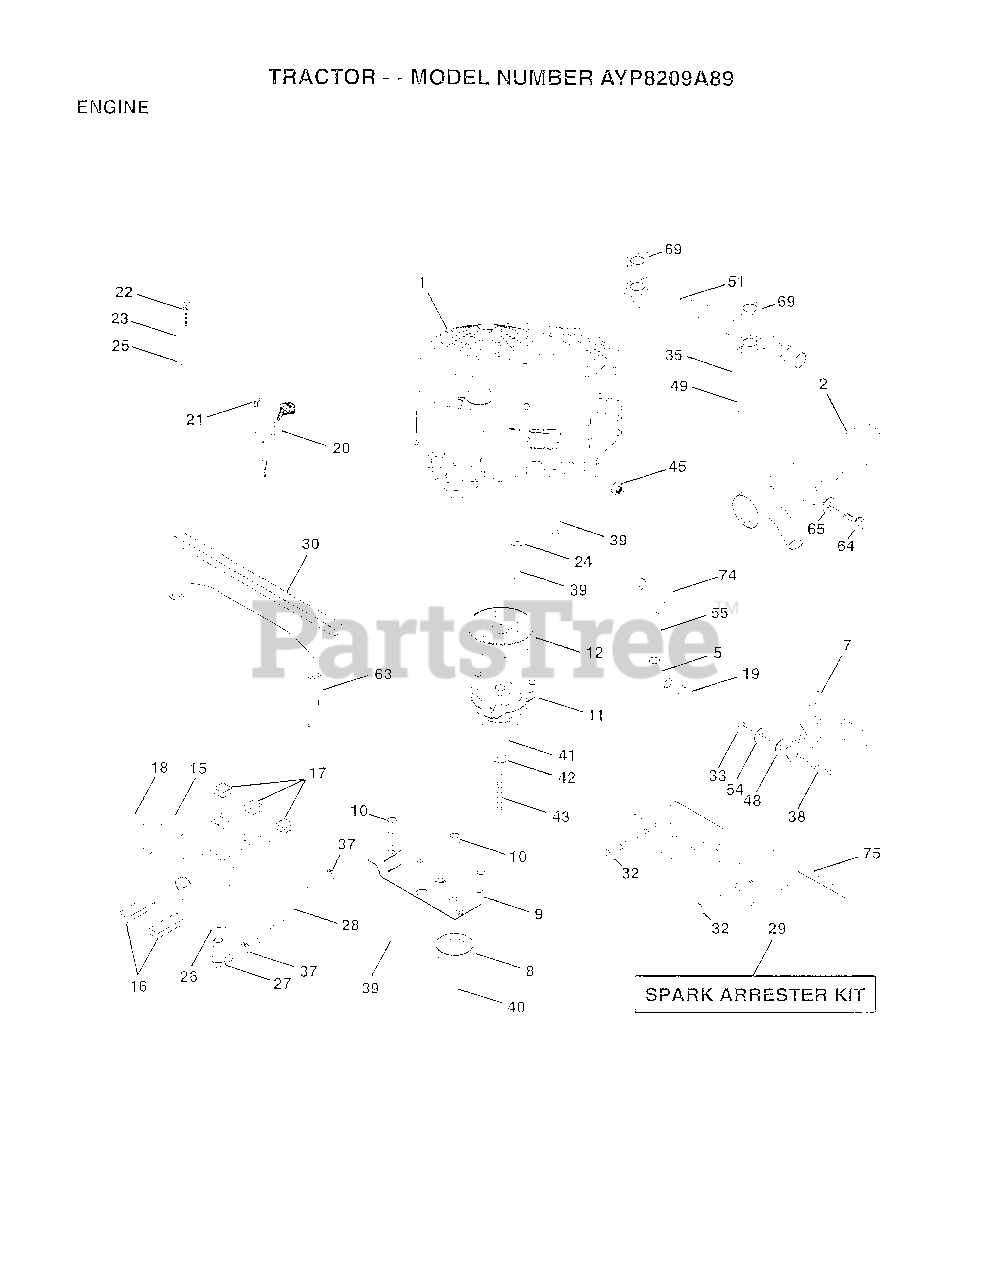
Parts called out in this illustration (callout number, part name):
2	MUFFLER SIDE1-1/8
4	PIPE NIPPLE LT
5	ELBOW
7	GUARD.MUFFLER.ASM
9	KEEPER ASM BELT
10	BUSHING.
12	PULLEY.ENG.CLUTCH
15	TANK FUEL REAR
16	PAD IDLER TI
17	PAD-SPACER LT
18	CAP ASM FUEL
19	PLUG T
21	SCREW LT
22	CHOKE CONTROL
23	WASHER
24	LOCKWASHER
25	"NUT,KEPS 3/8-24IM"
26	BUSHING OUTLET T
27	STEM.TANK.FUEL
29	SPARK ARREST KIT
30	FOAM-STRIP LT
35	LOCKWASHER
37	HOSE CLAMP
38	"BOLT,HEX"
39	SCREW.3/8-16X2.25
40	SCREW.TT.3/8-16X4
41	WASHER
42	LOCKWASHER
43	BOLT.7/16-20X4.25
45	NUT
47	SPACER.ENGINE
48	WASHER T
49	SCREW
51	PIPE.MANIFOLD
54	WASHER
63	HEAT.SHIELD.VGT.
64	SCREW
65	WASHER
69	GASKET MUFFLER
74	ELBOW STREET BASS
75	SHIELD.HEAT.INTEK.VGT
